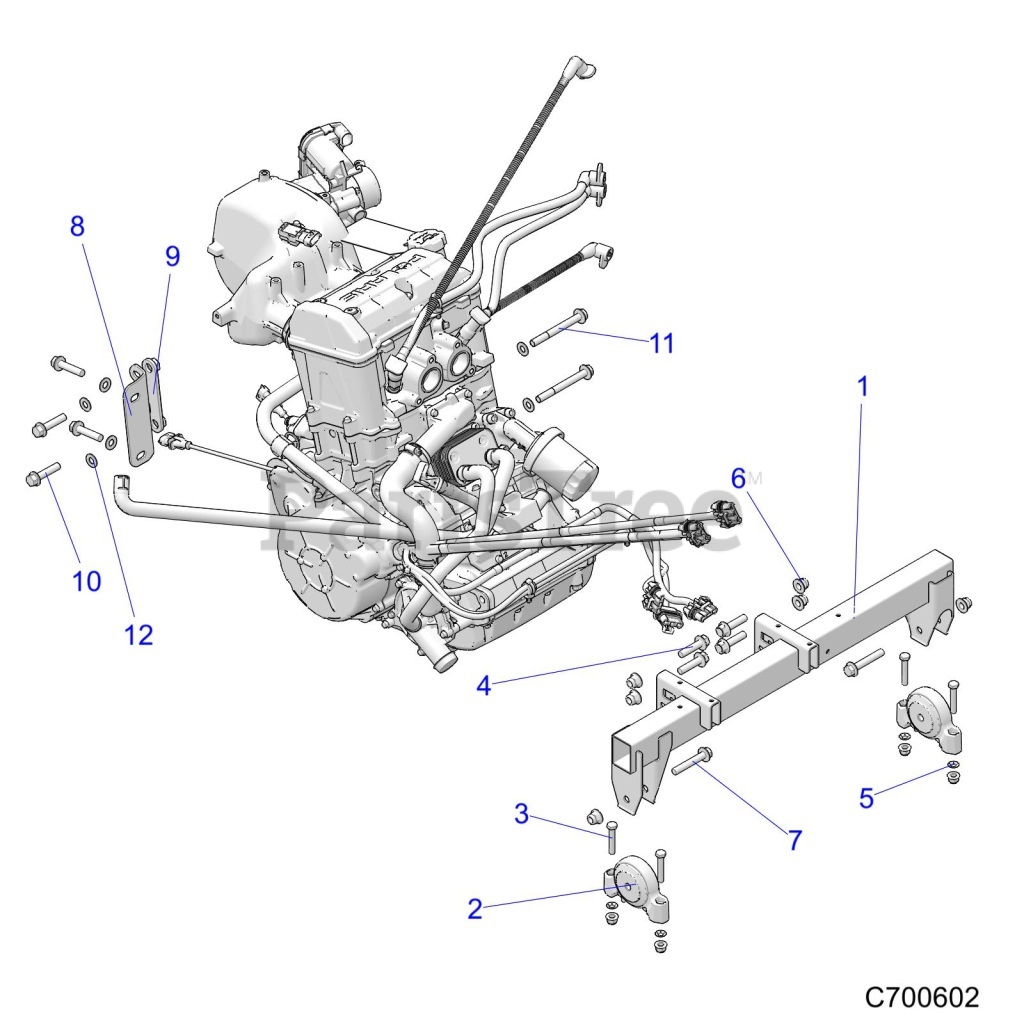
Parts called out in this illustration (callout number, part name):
1	WELD-MOUNT,ENGINE,BLK
2	MOUNT-ISOLATOR,DRIVELINE
3	SCR-HH M8X1.25X45 8.8 ZOD
4	NUT-M8X1.25,FLG,NYLOC-OLIVE D
6	NUT-M10X1.25,FLG,NYLOC-OLIVE D
7	BOLT-M10X1.25X60,HXFLG-OLIVE D
8	BRKT-COUPLER,TRANS
9	WELD-NUT,PLATE
10	SCR-HXFL-M10X1.25X45 8.8 ZOD
11	SCR-HXFL-M10X1.25X95 10.9 ZOD
12	WASHER,3/8 FW
